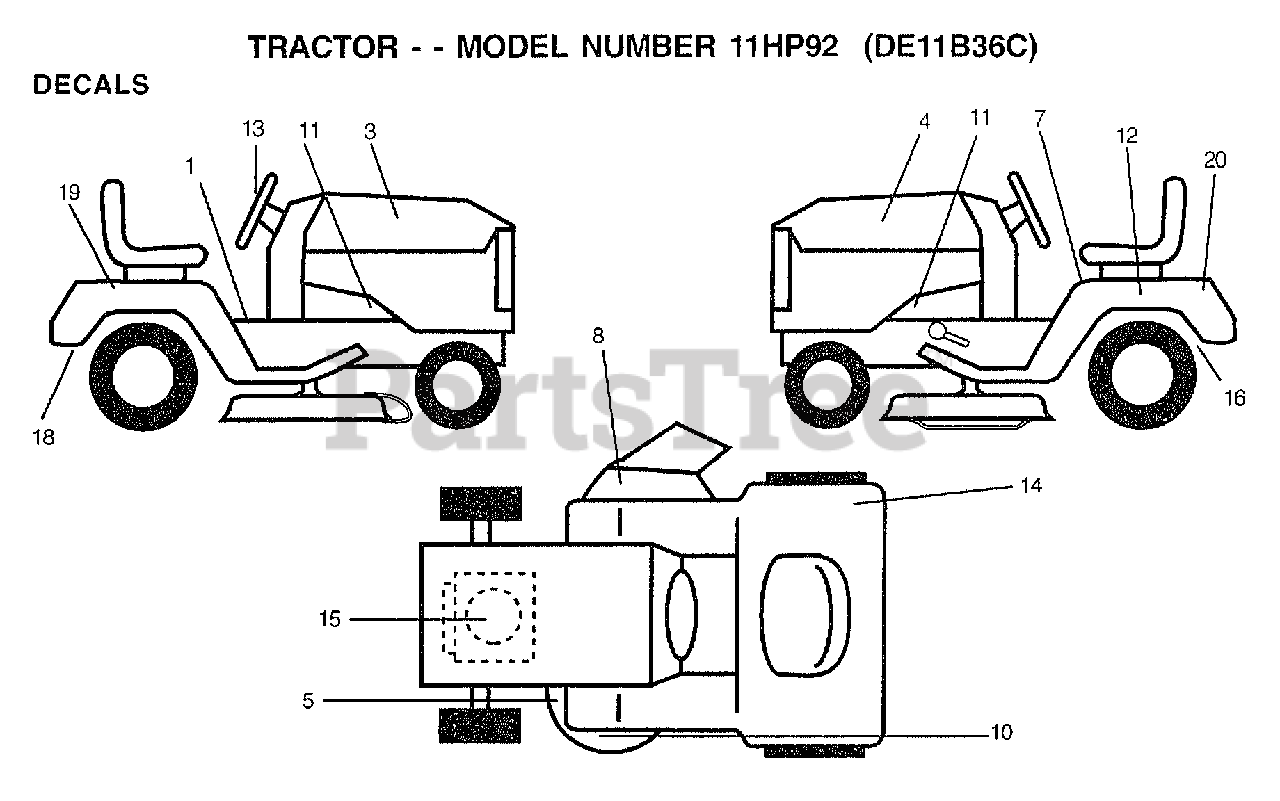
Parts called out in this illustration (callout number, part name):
1	DECAL CLUTCH/BRAK
3	DECAL.HOOD.RH
4	DECAL.HOOD.LH
5	DECAL.V.BELT
7	DECAL.READ.O.MANU
8	DECAL.DANGER.CUTF
10	DECAL.DECK.MOWER
11	"DECAL CHASSIS,HOT"
12	DECAL.BATRY.3-3908
13	DECAL.INST.STEERING
15	DECAL, ENGINE
16	DECAL.DRAWBAR.LDL
18	DECAL.EURO.ST.CE.
19	DECAL.FENDER.RH
20	DECAL FENDER LH
